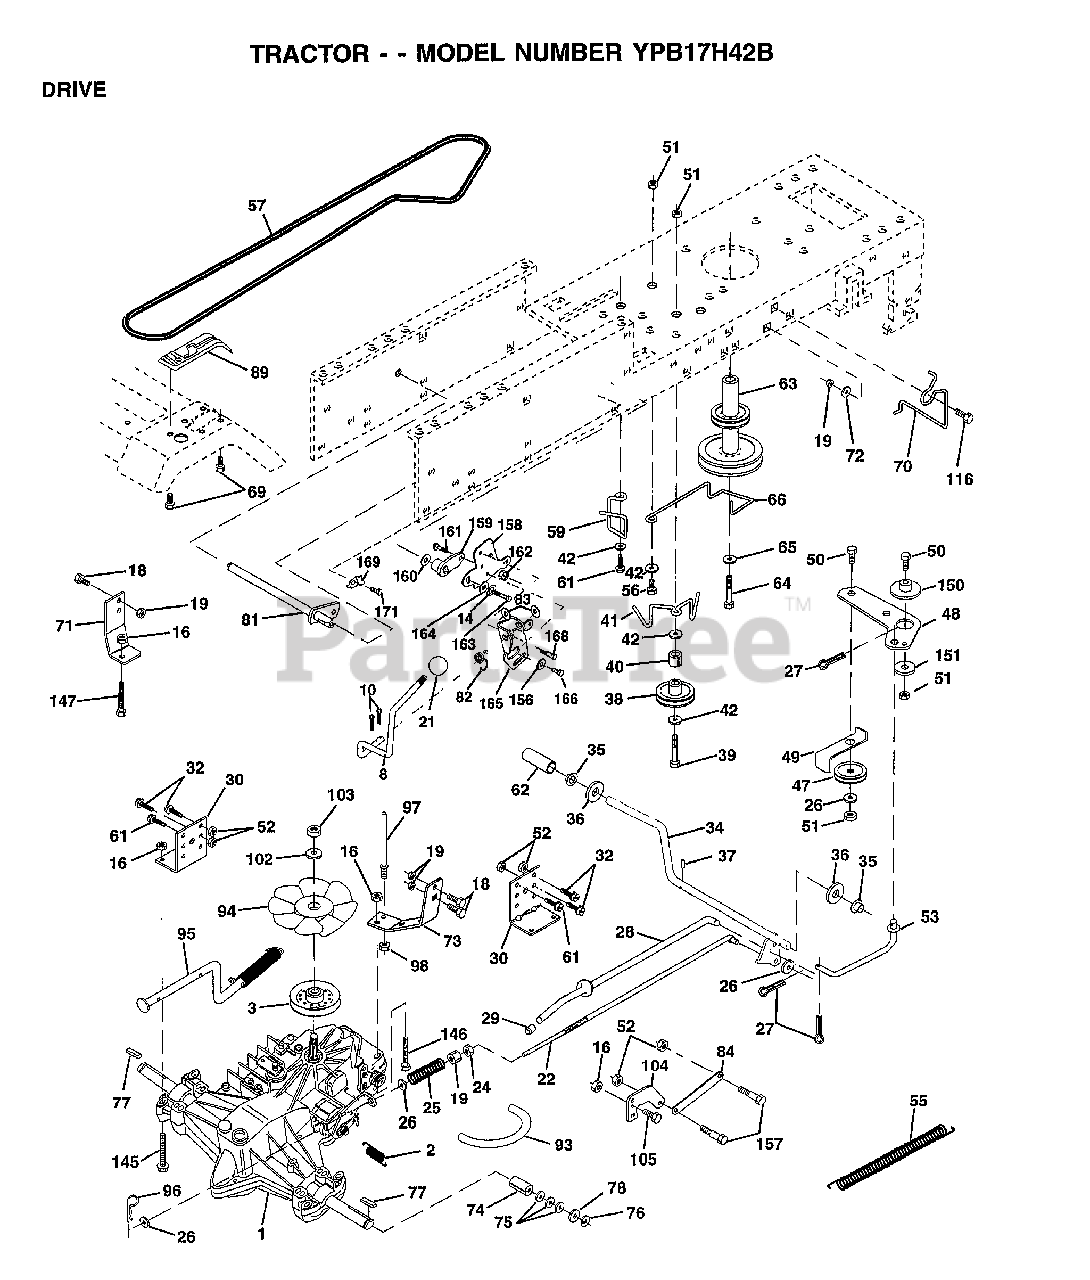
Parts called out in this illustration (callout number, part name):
2	SPRING RET BRAKE
3	PULLEY.TRANSAXLE
8	ROD.SHIFT.FENDER.ADJ.LT.CRD
10	PIN COTTER 1/8
14	LOCKWASHER
16	NUT
18	BOLT
19	NUT
21	KNOB DLX BLK/BLK
22	ROD.BRAKE.HYDRO.
24	NUT HEX JAM 3/8-16
25	SPRING ROD LT
26	WASHER
27	COTTER PIN
28	ROD.BRAKE.PARK.LT
29	PLUNGER CAP T
30	TRANSAXLE MTG BKT
32	BOLT
34	SHAFT ASM-PEDAL F
35	NYLON BEARING
36	WASHER LT
38	FLAT IDLER PULLEY
39	BOLT
40	SPACER T
41	"KEEPER,BELT.IDLER FLAT"
42	WASHER
48	BELLCRANK.CLUTCH
49	RETAIN BELT
53	"LINK, CLUTCH T"
55	"SPRING, RETURN LT"
57	"BELT.GD DRV 82"""
59	KEEPER BELT CNTSP
61	SCREW
62	"COVER,PEDAL"
63	PULLEY.ENGINE
64	BOLT
65	LOCKWASHER
66	KEEPER-BELT
69	SCREW HEXWSH H-L
70	KEEPER BELT ENG
71	STRAP TORQ LH HYD
72	WASHER
73	"STRAP-TORQUE,RH"
74	SPACER SPLIT
75	WASHER
76	E-RING LT
77	SQUARE KEY
78	WASHER
81	SHAFT.ASM.CROSS
82	"SPRING,TORSION"
83	WASHER
84	LINK.TRANSAXLE.LT/YT
89	CONSOLE.SHIFT.LT
93	"LINE FUEL HYD 4"""
94	"FAN 7"" HYDRO"
95	CONTROL.ASM.BYPASS.HYDRO.99
96	RETAINER M
97	BOLT KEEPER RH
98	NUT
102	WASHER BELLEVILLE
104	ARM CONTROL HYDRO
105	SCREW CAP 5/16-18
116	BOLT RDHD 3/8-16
145	BOLT.HEX.FLGHD
146	BOLT.HEX.FLGHD.
147	BOLT.HEX.FLGHD
150	BUSHING.BELLCRANK.GRD.DR
151	WASHER
156	WASHER.SRRTD.5/16
157	"BOLT,SHOULDER"
158	BRKT.SHIFT.MOUNT
159	HUB.SHIFT
160	WASHER
161	BOLT T
164	WASHER.5/8X.281X10GA
165	BRKT.PIVOT.LEVER
166	SCREW.5/16-18X5/8
168	BOLT.SHOULDER.5/16-18X.561
169	PLATE.FASTENING
171	SCREW LT
